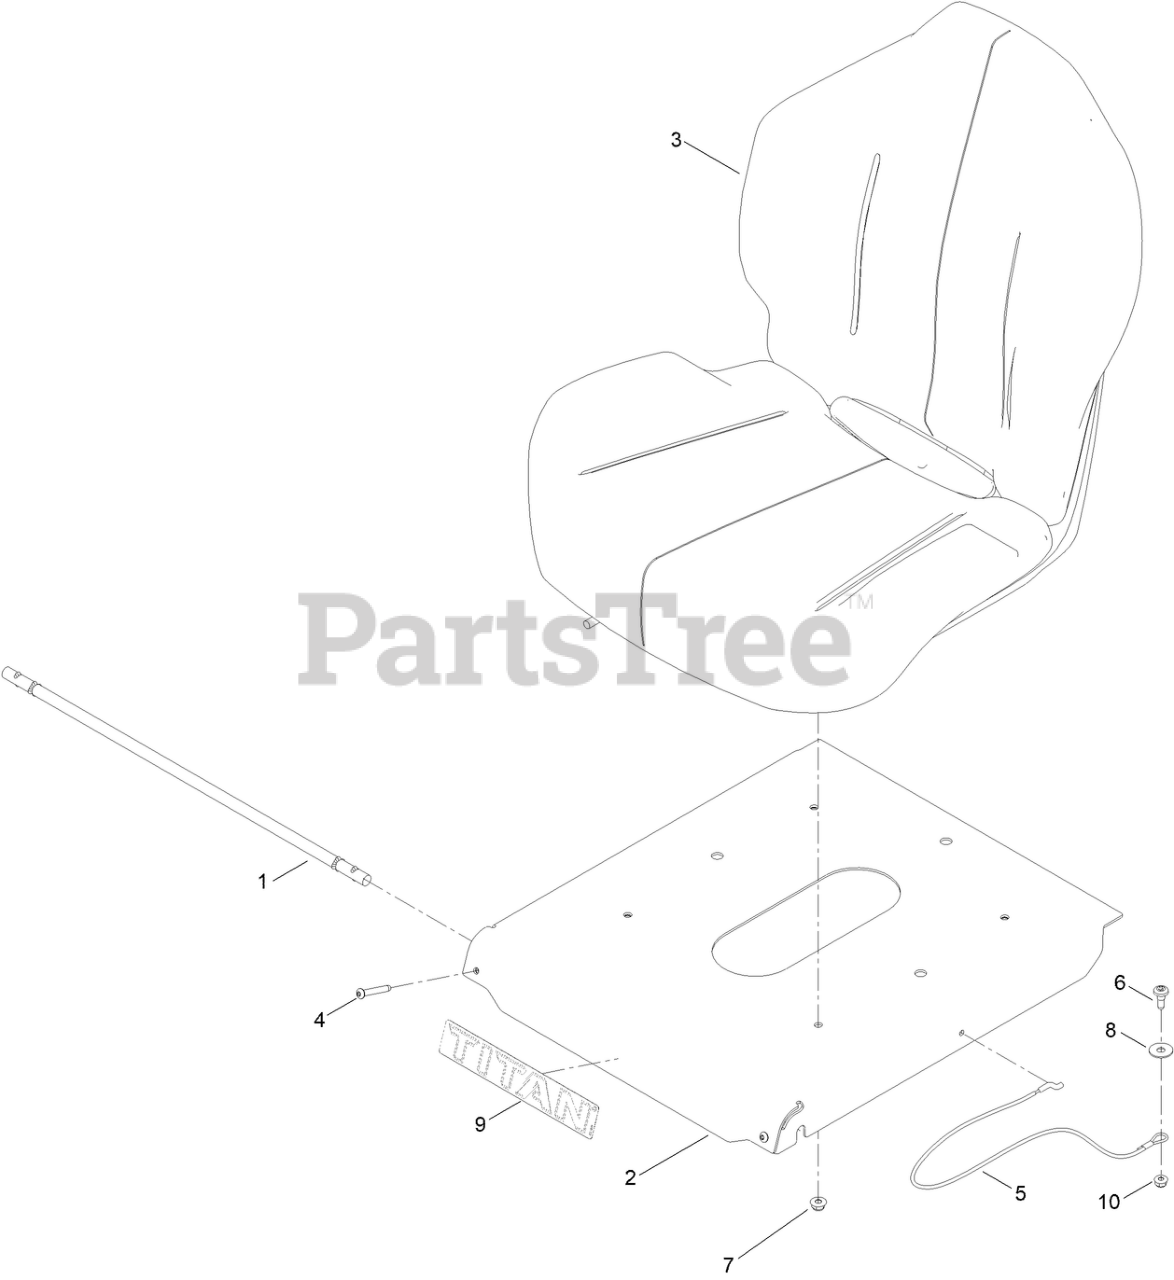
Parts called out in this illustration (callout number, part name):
1	ROD-PIVOT
2	PAN-SEAT
3	SEAT ASM - MILSCO CS180D
4	SCREW-TBH,THD ROLL
5	CABLE-LANYARD, 26.75"
6	SCREW-SHOULDER
7	NUT-HF
8	WASHER-FLAT
9	DECAL-TITAN
10	NUT-FLANGE, NI
